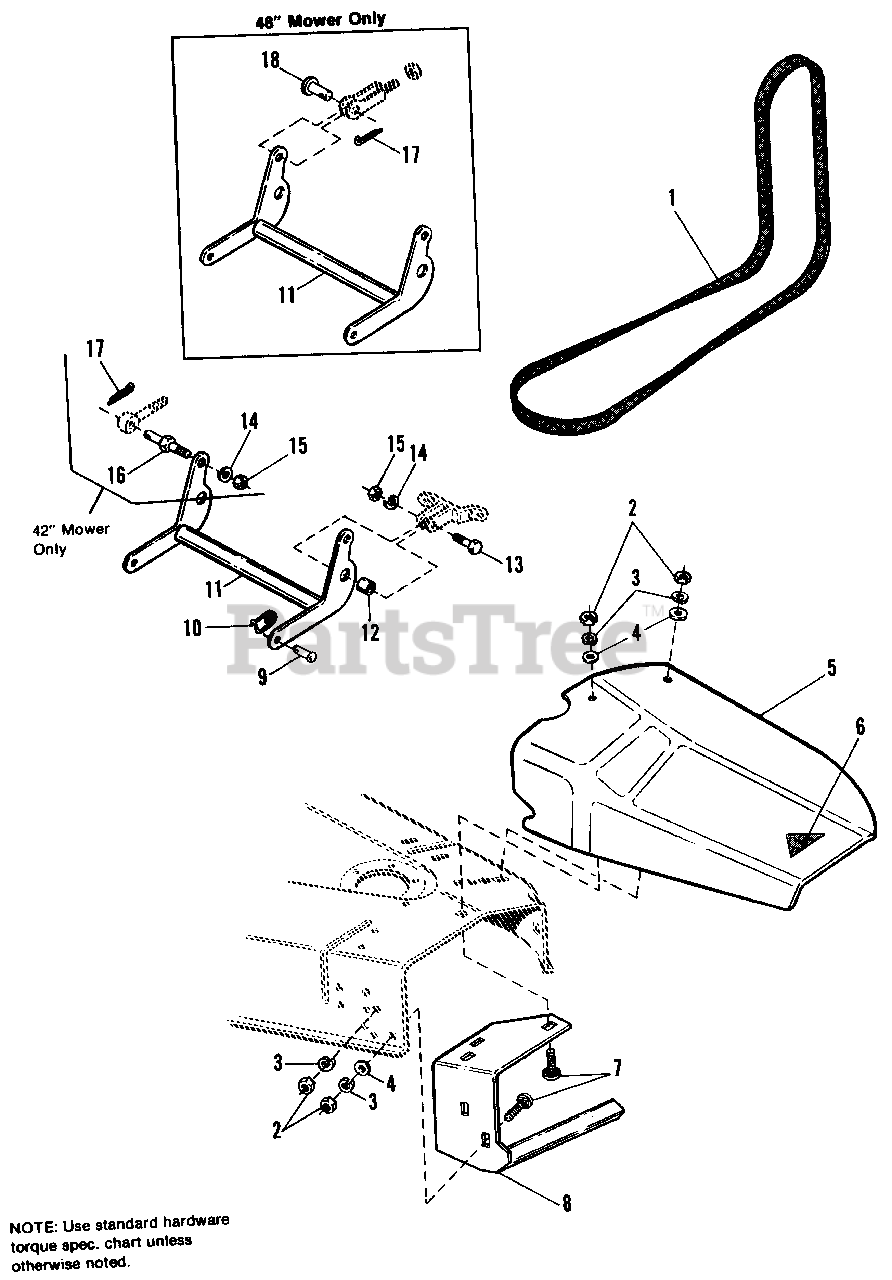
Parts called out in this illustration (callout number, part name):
1	V-BELT, PTO to Mower, 42" Mower
1	BELT, PTO to Mower, 48" Mower
2	NUT, Hex, 3/8-16
3	LOCKWASHER, 3/8
4	WASHER, Special
5	DEFLECTOR, 42" Mower (Orange)
5	DEFLECTOR, 42" Mower (Black)
5	DEFLECTOR, 48" Mower (Orange)
5	DEFLECTOR, 48" Mower (Black)
6	DECAL, OPEI
7	CARRIAGE BOLT, 3/8-16 x 1-1/4
8	GUARD ASSY., Stone, 42" Mower
8	GUARD ASSY., Stone, 48" Mower
10	PIN, Clip
11	ROCKER ARM ASSY.
13	CAPSCREW, Hex Hd., 1/2-13 x 1-1/4
14	LOCKWASHER, 1/2 (Qty. 2 on 48" Mower)
15	NUT, Hex, Jam, 1/2-13 (Qty. 2 on 48" Mower)
16	PIN, Pivot (42" Mower Only)
17	PlN, Cotter, 1/8 x 1
18	PlN, Yoke,(48" Mower Only)
